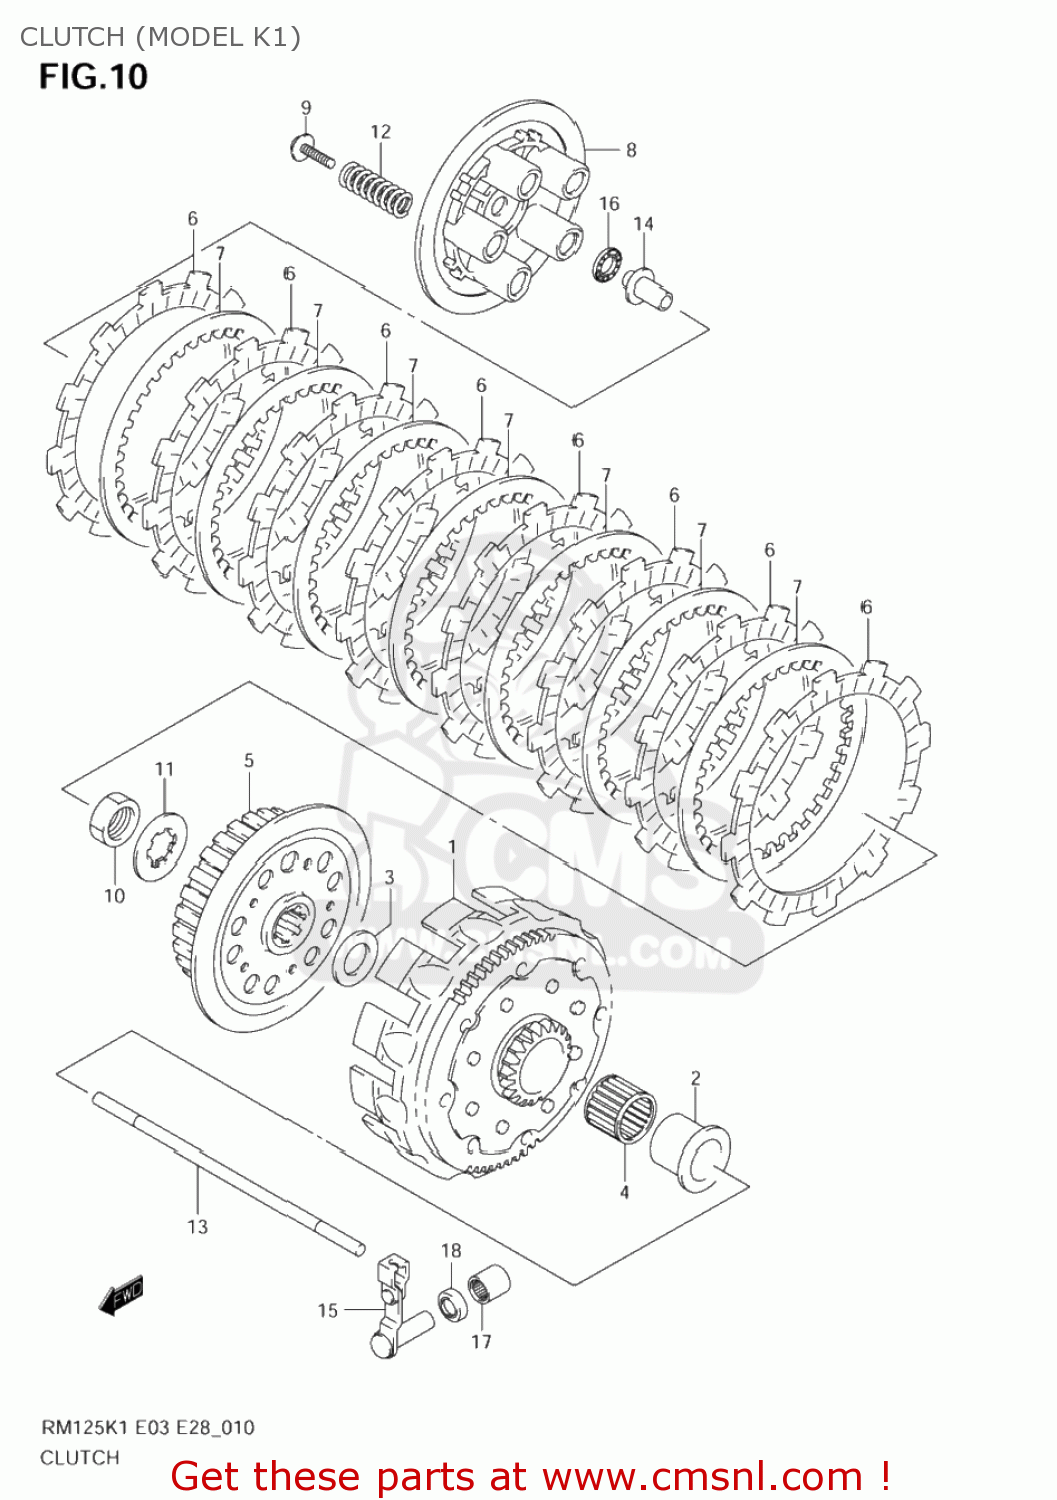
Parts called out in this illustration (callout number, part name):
1	GEAR ASSY,PRI DRIVEN
2	SPACER,PRIMARY DRIVEN GEAR
3	WASHER
4	BEARING(25X30X22)
5	HUB,CLUTCH SLEEVE
6	PLATE,CLUTCH DRIVE(T:2.8) (NAS)
7	PLATE,CLUTCH DRIVEN(T:1.4) (NAS)
8	DISC,CLUTCH PRESSURE
9	BOLT(5X25)
10	NUT
11	WASHER,LOCK
12	SPRING
13	ROD,CLUTCH PUSH
14	PIECE,CLUTCH PUSH
15	CAMSHAFT,CLUTCH RELEASE
16	BEARING(10X22X2.8)
17	BEARING(10X14X15)
18	SEAL,OIL(10X17X5)
